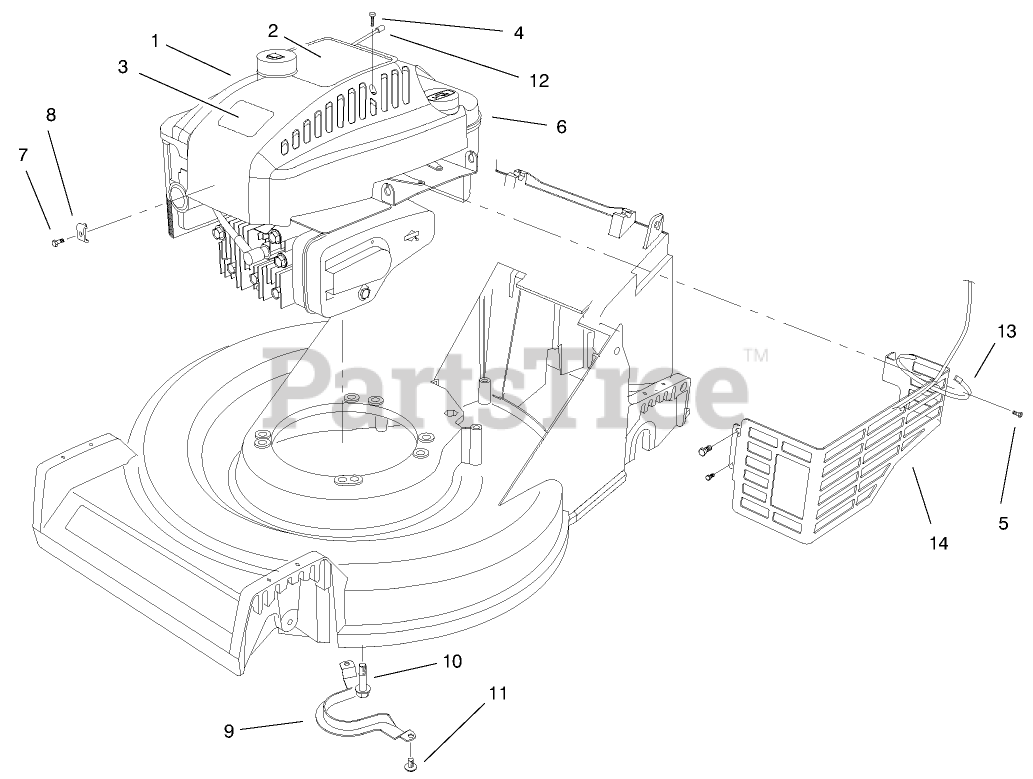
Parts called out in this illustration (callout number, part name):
1	SHROUD-ENGINE
2	DECAL - RECOIL
3	DECAL
6	Engine-Quantum 6.0 Hp
7	SCREW-CLAMP
8	CLAMP-CASING
10	SCREW-HWH
11	SCREW-HWHTF
12	STOP-ROPE
13	TIE-CABLE
